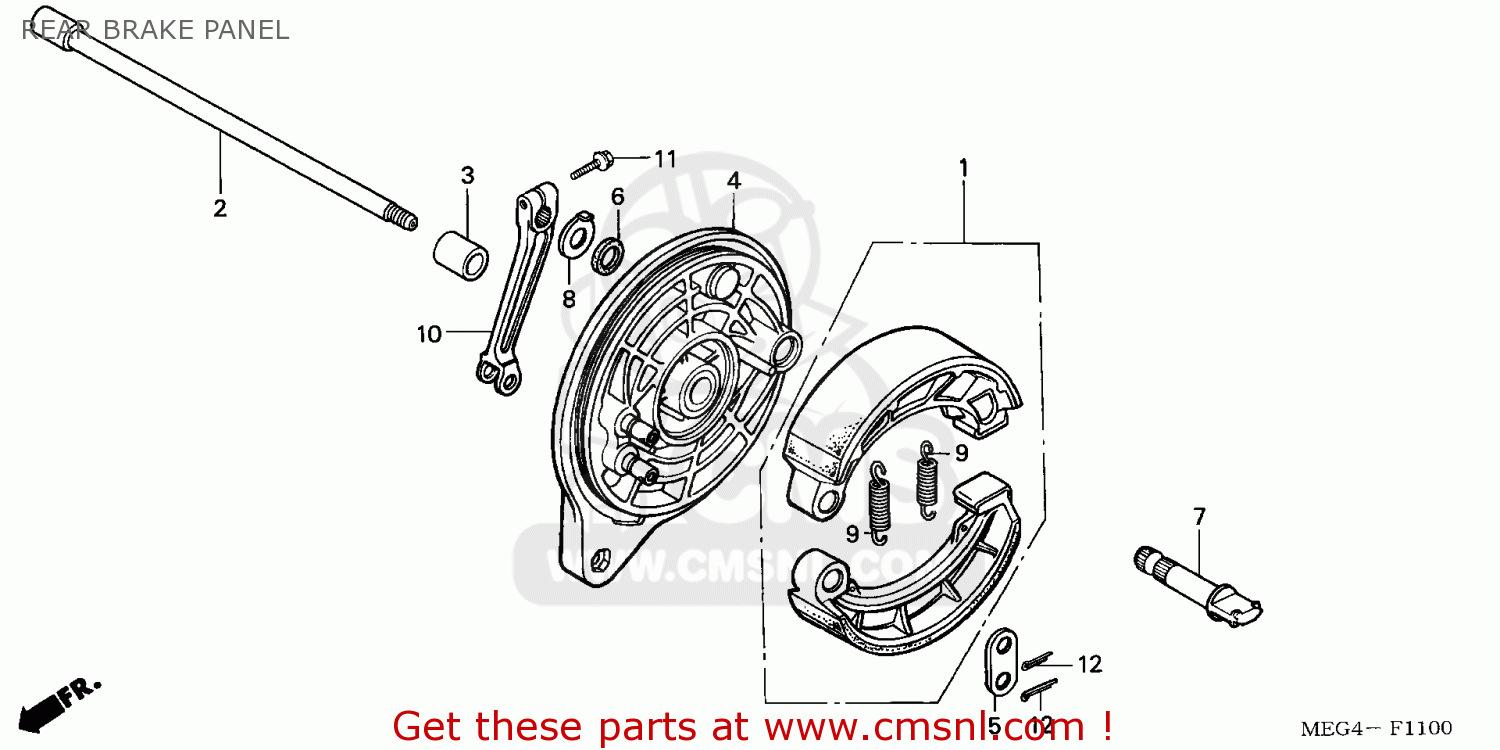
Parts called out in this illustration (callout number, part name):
1	SHOE SET,BRAKE (NAS)
2	AXLE,RR WHEEL
3	COLLAR, BRK PANE
4	PANEL CO*NH109MS*
5	WASHER,ANCHER PIN
6	SEAL BRAKE CAM
7	CAM,REAR BRAKE
8	INDICATOR,RR.BRK.
9	SPRING,RR.BRAKE
10	ARM,RR BRAKE
11	BOLT,FLANGE,8X25
12	PIN COTTER 2.5MM
